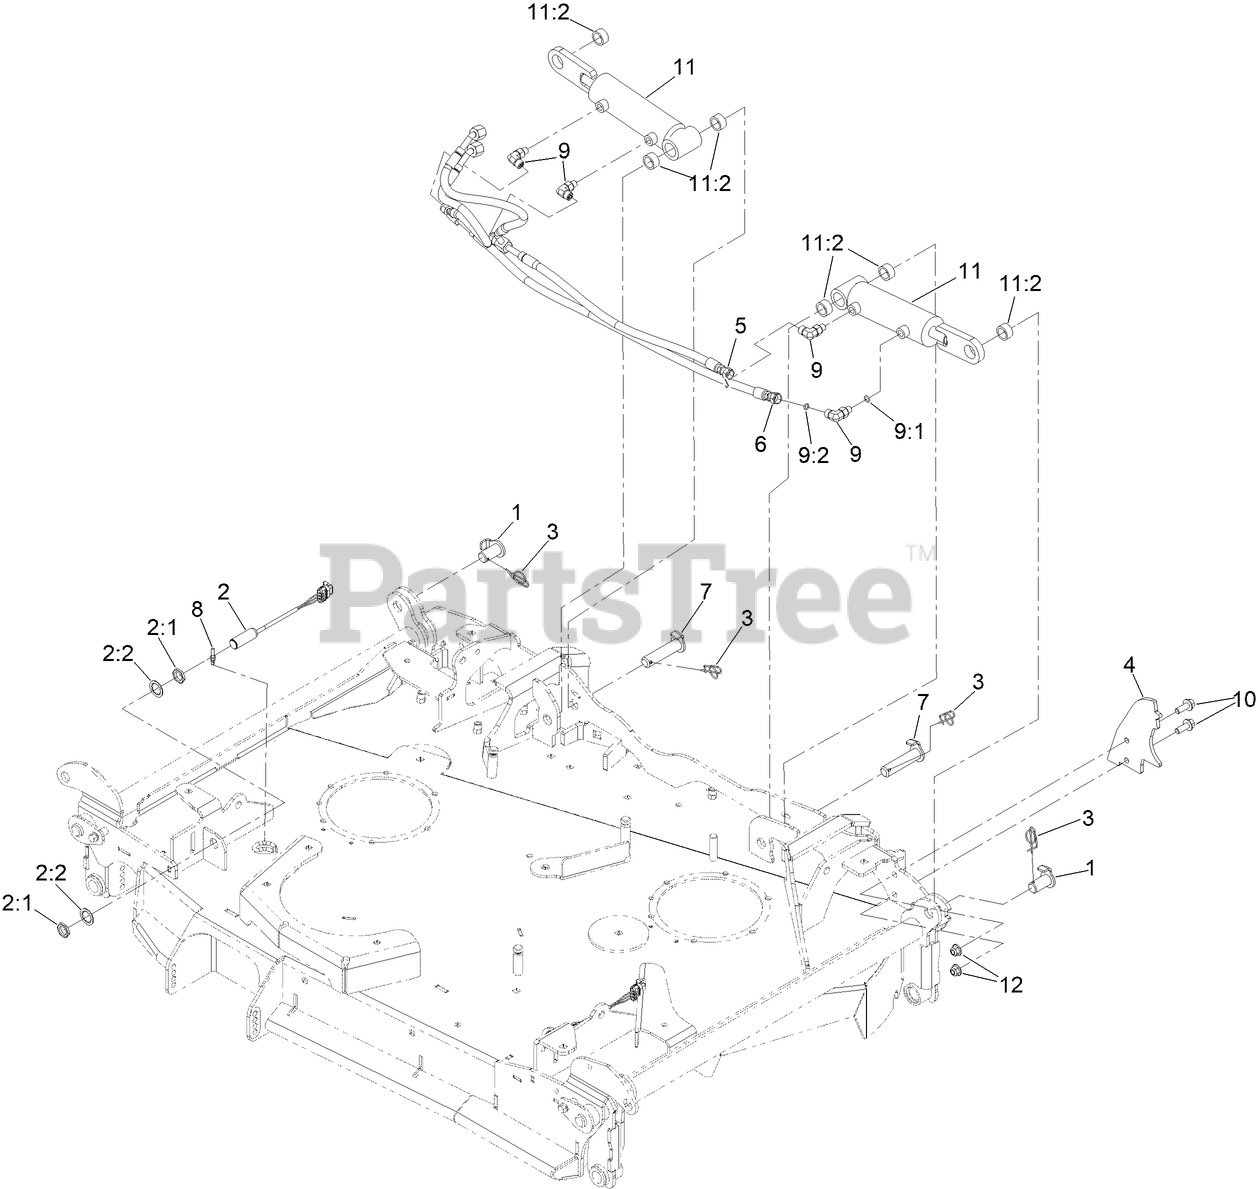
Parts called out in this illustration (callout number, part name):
1	PIN-CYLINDER
2	PROXIMITY SWITCH ASM
2:1	NUT-HEX
2:2	WASHER-LOCK, INTERNAL TOOTH
3	PIN-LOCKING COTTER
4	BRACKET-DECK STOP LH
5	HOSE ASM
6	HOSE ASM
7	ASM-CYL PIN BASE
8	TIE-CABLE
9	FITTING-ELBOW, 90 DEG
9:1	O-RING
9:2	O-RING
10	SCREW-HHF
11	CYL-DECK FOLD
11:2	BUSHING-0.75X1.00X0.50 LONG
12	NUT-HF, NI
